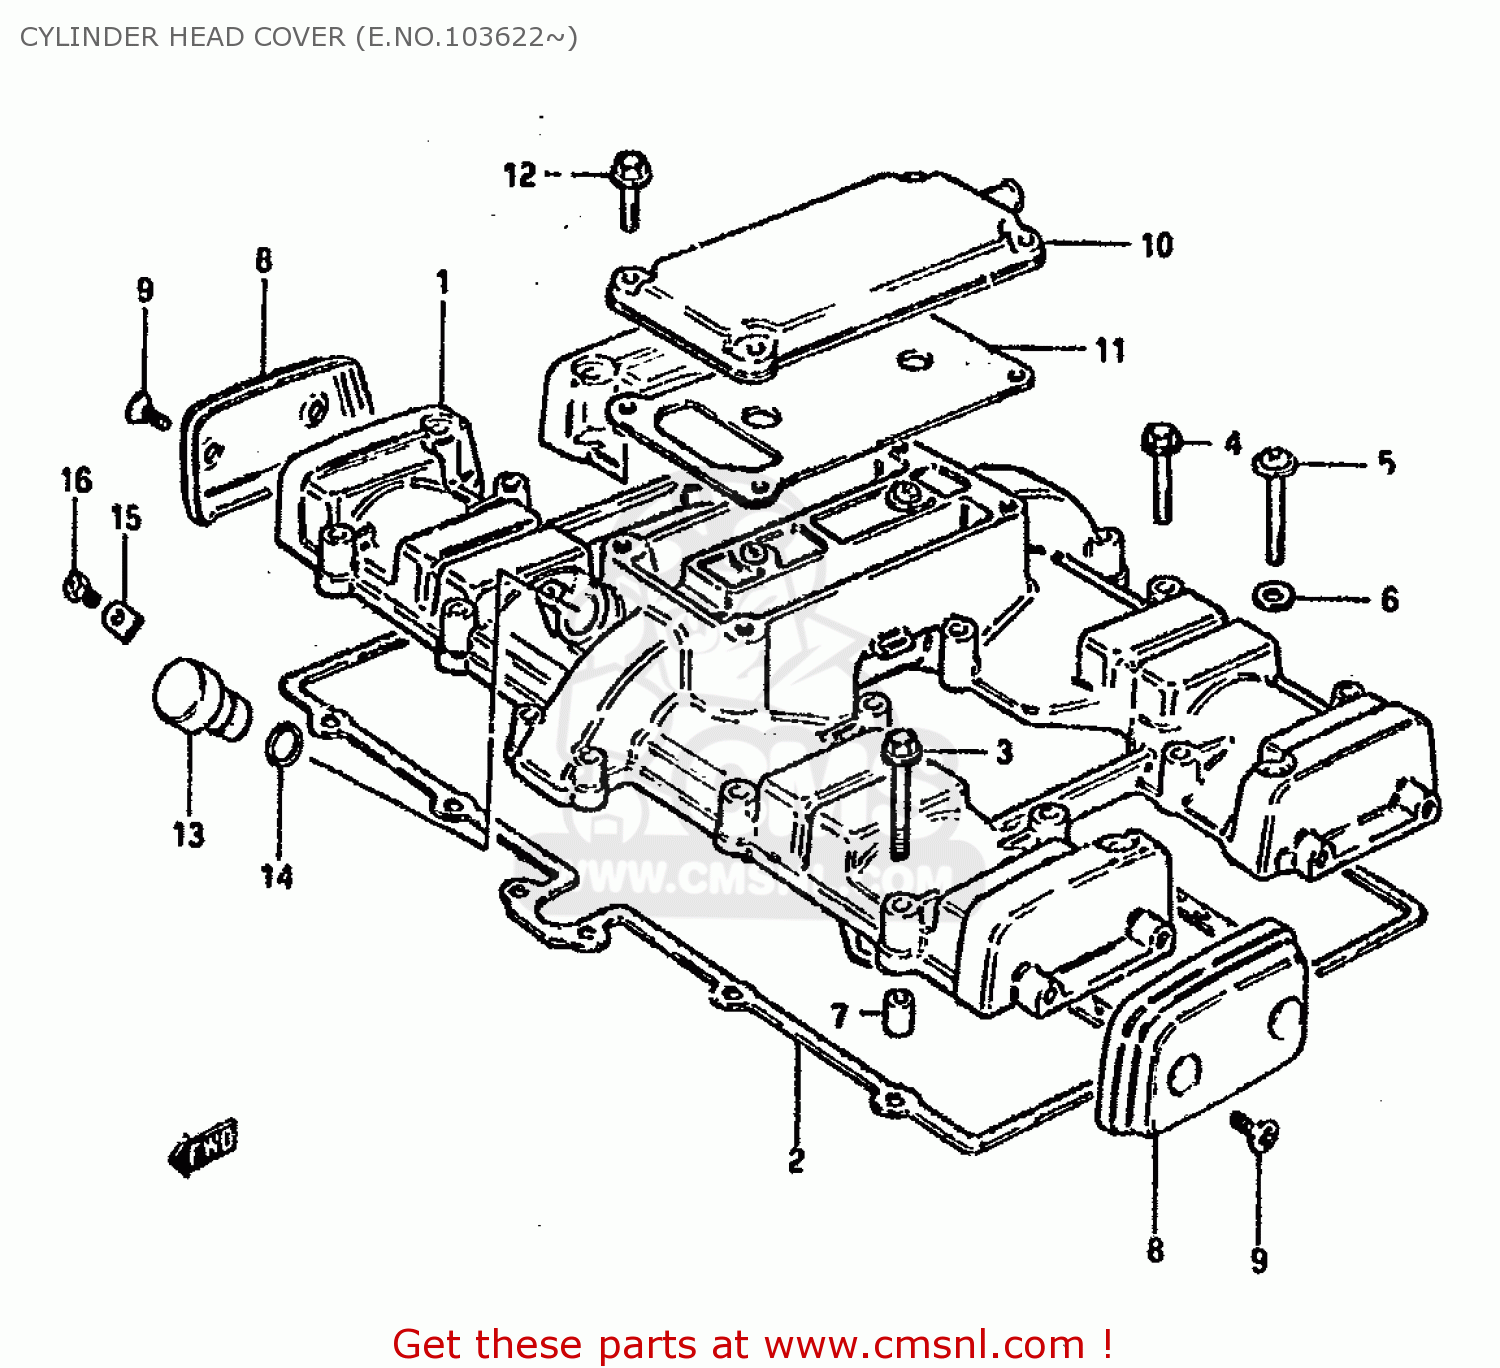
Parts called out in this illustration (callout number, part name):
1	COVER,CYLINDER HEAD
2	GASKET,CYLINDER HEAD COVER (MCA)
3	BOLT
4	BOLT 6X35
5	SCREW 6X40
6	GASKET (NAS)
7	PIN(6.2X8X11)
8	CAP,CYLINDER HEAD COVER
9	SCREW(5X12)
10	COVER,BREATHER
11	GASKET (MCA)
12	BOLT,REAR
13	PLUG,TACH GEAR SLEEVE HOLE
14	SEAL,TACHOMETER DRIVEN
15	PLATE,TACH DRIVE GEAR SLEEVE
16	SCREW(5X12)
